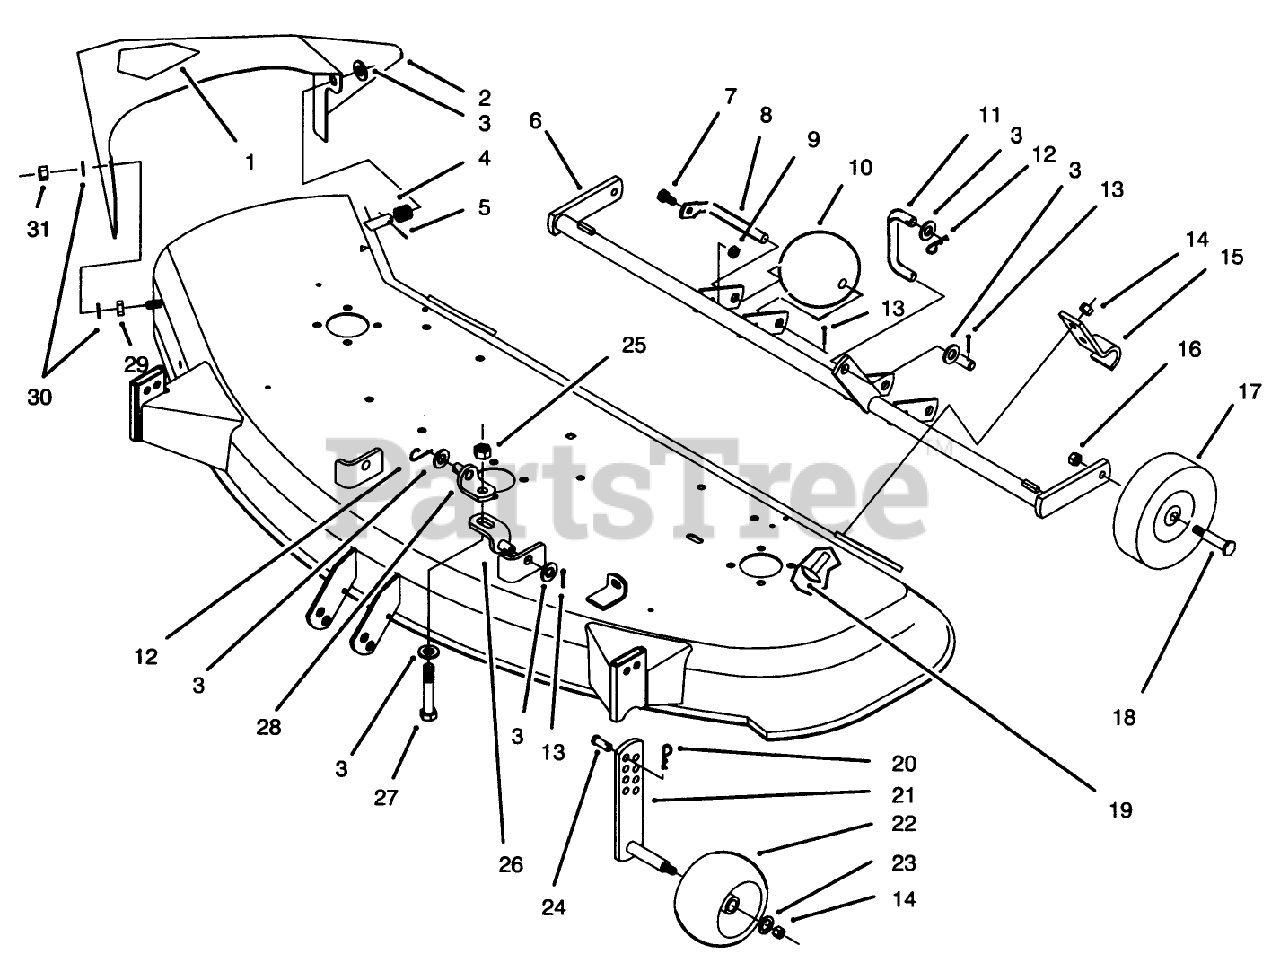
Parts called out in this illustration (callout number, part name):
1	DECAL-DANGER
2	Chute & Decal ASM (Incl. Ref. #1)
3	WASHER-FLAT
4	SPRING-DEFLECTOR
5	PIN-COTTER
6	SUPPORT-GAGE WHEEL
7	SCREW-HH
8	SHAFT-ROLLER
9	NUT-LOCK, NI
10	ROLLER
11	LINK-REAR
12	Hairpin
13	PIN-COTTER
14	NUT-LOCK, NI
15	Clamp
16	NUT-HEX
17	WHEEL
18	BOLT-SHOULDER
19	BOLT-CARR
20	Hairpin Cotter
21	GAGE-WHEEL
22	WHEEL-GAGE
23	WASHER-FLAT
24	PIN-CLEVIS
25	NUT-JAM
26	BRACKET-LIFT, LOWER
27	SCREW-HH
28	BRACKET-LIFT, UPPER
29	BUSHING-PIVOT
30	WASHER
31	NUT-HJ
